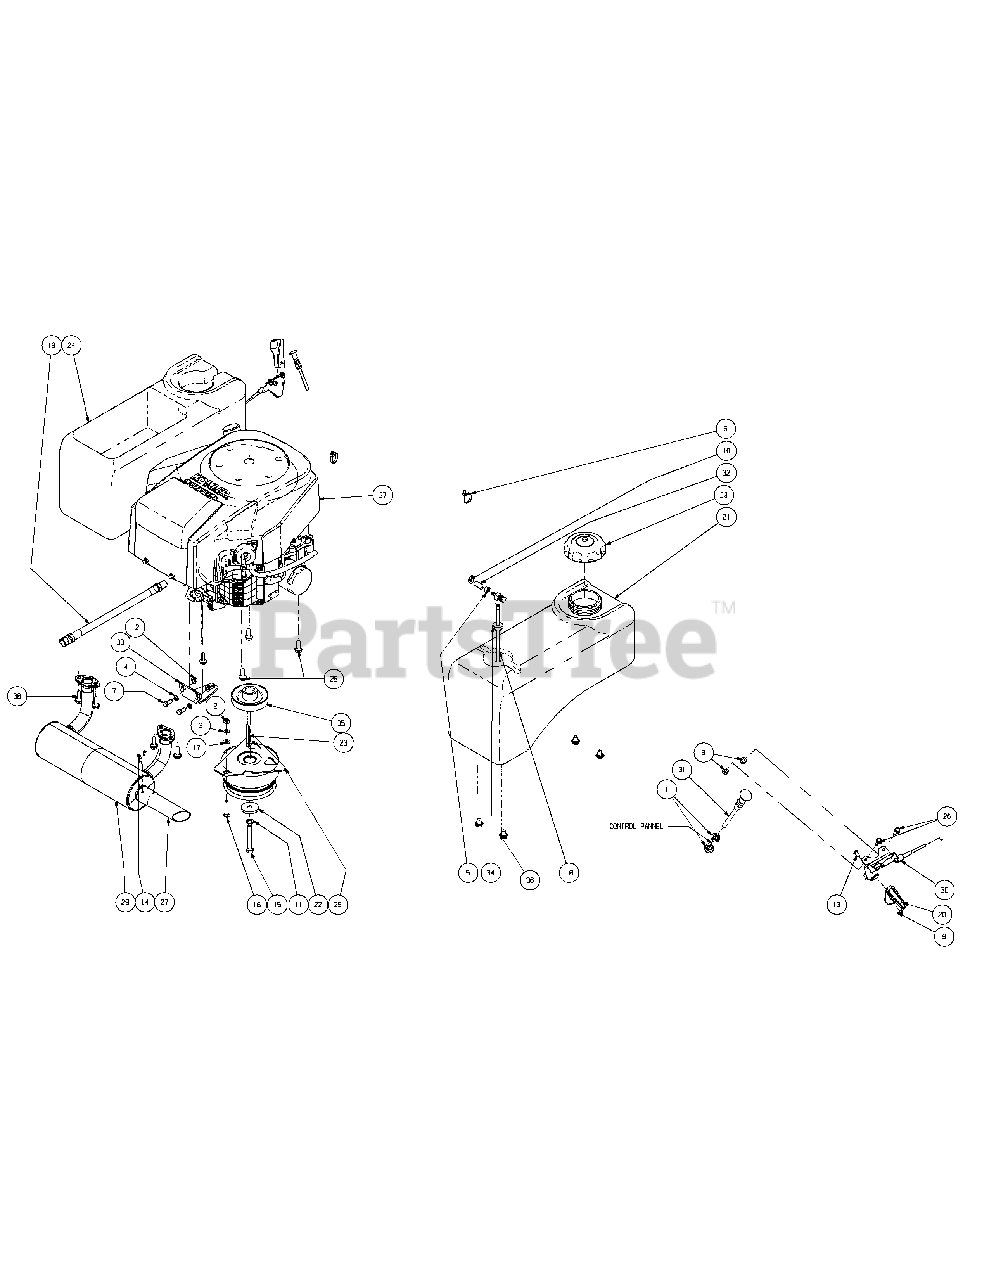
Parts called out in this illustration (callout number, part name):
1	Hex Jam Nut, 3/8-24
2	Hex Nut, 5/16-18
3	Lock Washer, 5/16
4	Flat Washer, 5/16
5	Clamp, Union
6	Cable Tie, 3/16 x .05 x 7.4
7	Hex Cap Screw, 5/16-18 x .75
8	Lock Nut, Nylon Insert, 10-32
9	Nut, w/ Star Washer
10	Hose Clamp, 1/4-5/8, SS
11	Lock Washer, 7/16
12	Lock Nut, Hex Flange, 5/16-18
13	Machine Screw, 8-32 x .375
14	Screw, 8-32 x .375, Hex Washer
15	Hex Cap Screw, 7/16-20 x 3.0
16	Carriage Bolt, 5/16-18 x 1.75
17	Washer, 3/8 x .738 x .063
18	Fuel Pickup Fitting
19	Oil Drain Extension Hose
20	Throttle Control Knob
21	Fuel Tank
22	Flat Washer, 7/16 ID x 1.75 OD x .250
23	Key, 1/4 x 1/4 x 2.75
24	Utility Bin
25	Ogura DX11 Electric Clutch
26	Screw, #10-32 x 0.500
27	Exhaust Pipe
28	Self Tapping Screw, 3/8-16 x 0.875
29	Kohler Muffler
30	Throttle Control Cable
31	Choke Cable
32	Hose, 1/4" Fuel Line
34	Fuel Tank Groment
35	Transmission Drive Pulley
36	Hex Head Cap Screw, 3/8-16 x 1.00, Flange Whiz
37	25HP Kohler Engine
38	Hex Head Cap Screw, 5/16-18 x 1.00, Flange Whiz
39	Fuel Cap
